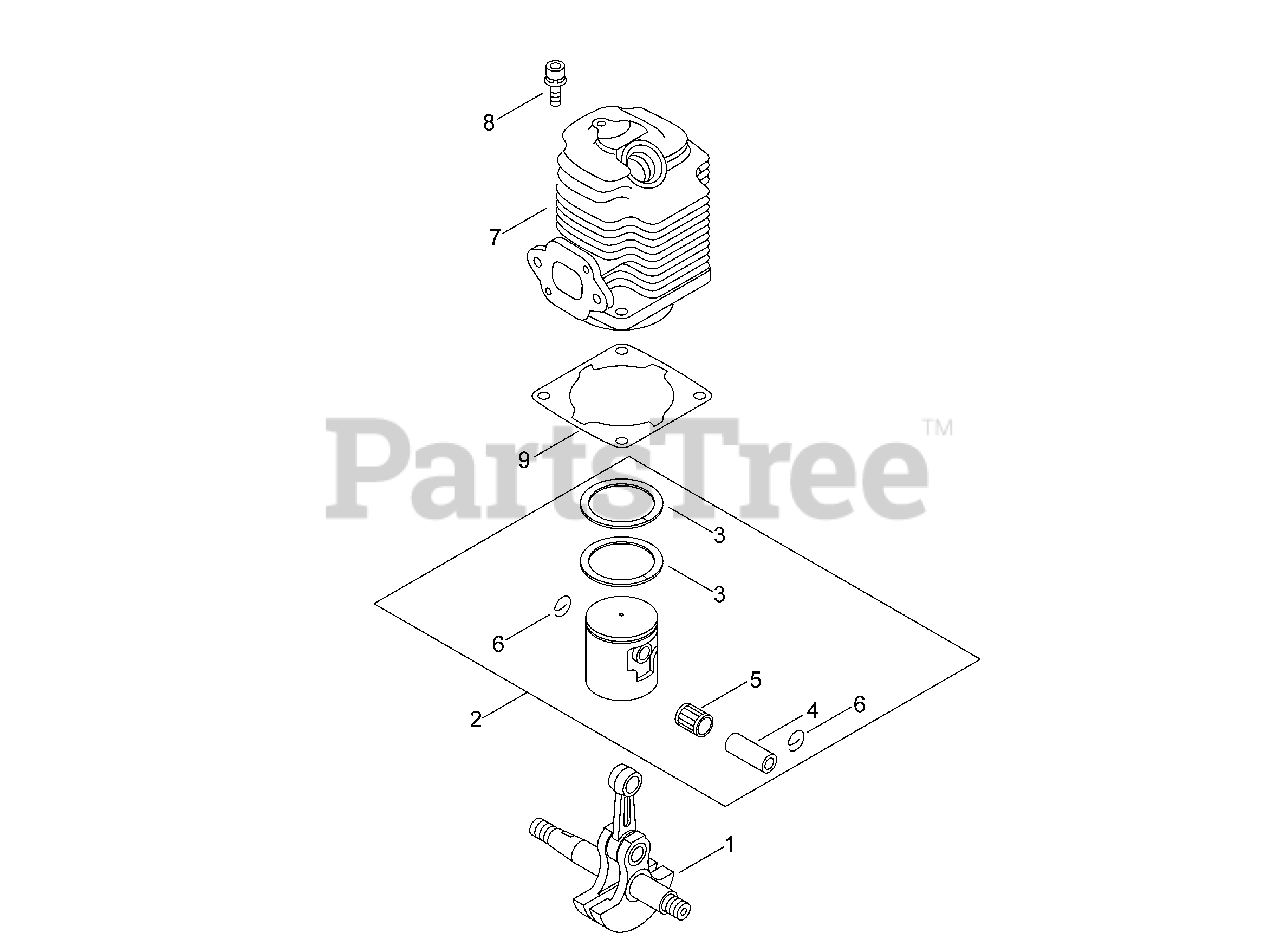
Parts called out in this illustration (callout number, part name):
1	CRANKSHAFT ASSY
2	PISTON KIT
3	+RING, PISTON
4	+PIN, PISTON
5	+BEARING, NEEDLE
6	+RING, SNAP Ø10
7	CYLINDER
8	BOLT 5×22
9	GASKET, CYLINDER
